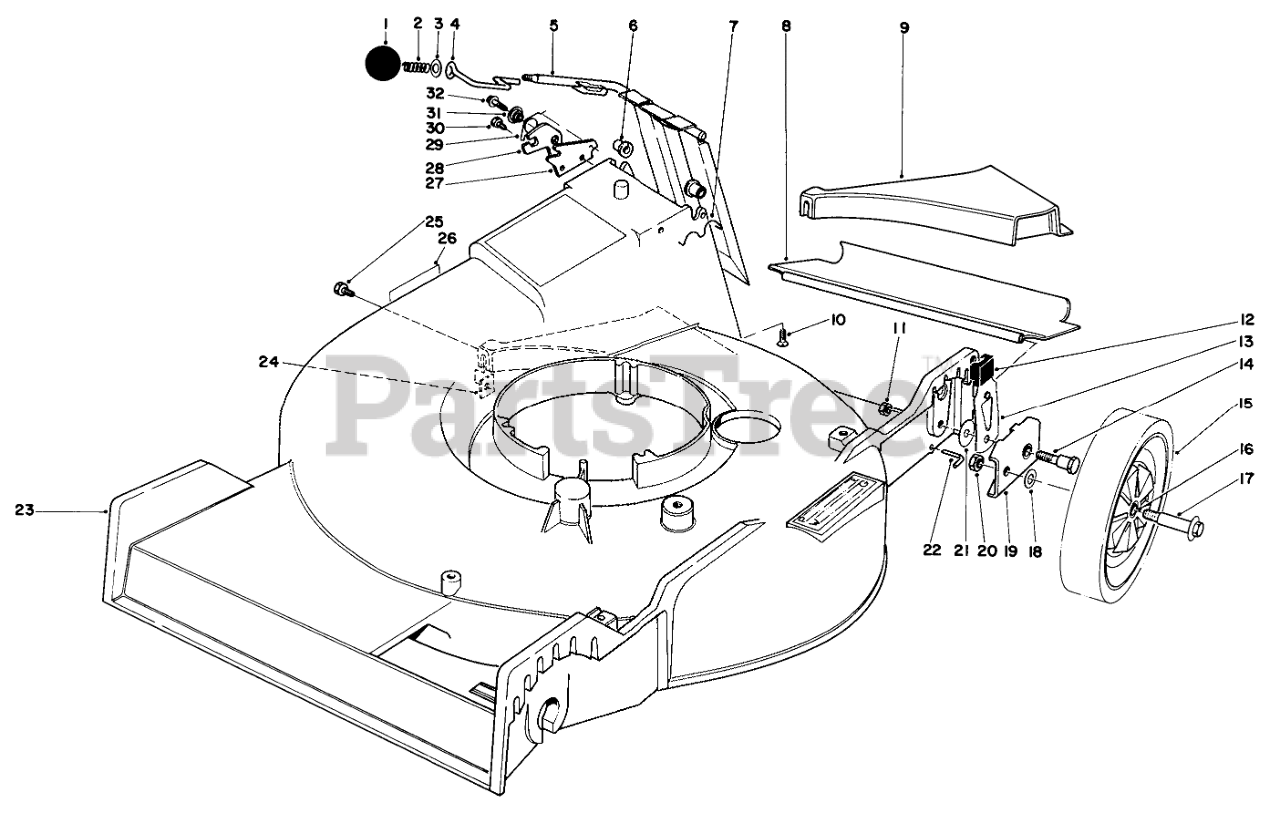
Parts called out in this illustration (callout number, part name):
2	COMPRESSION SPRING
3	WASHER-FLAT
4	DOOR LATCH
5	DOOR HANDLE WA
6	BUSHING-NYLON
7	DOOR RETAINER
8	REAR SAFETY SHIELD
9	REAR INSERT
10	SCREW-HH
11	NUT-LOCK, NI
12	KNOB-ARM
13	SPRING ARM ASM HP
14	PIVOT SCREW
15	Wheel & Tire Assembly (Incl. Ref. #16)
16	BUSHING
17	BOLT-WHEEL
18	WASHER
19	HP PIVOT ARM ASM
20	Nut
21	PIVOT WASHER
22	ROD-SHIELD
23	Housing (Incl. Ref. #26)
24	SPECIAL NUT
25	SCREW THD 1/4 20 5/8
26	DECAL-DANGER
27	DOOR LATCH PLATE
28	SAFETY LATCH
29	TORSION SPRING
30	SCREW-HWH
31	DOOR SPACER
32	Screw
